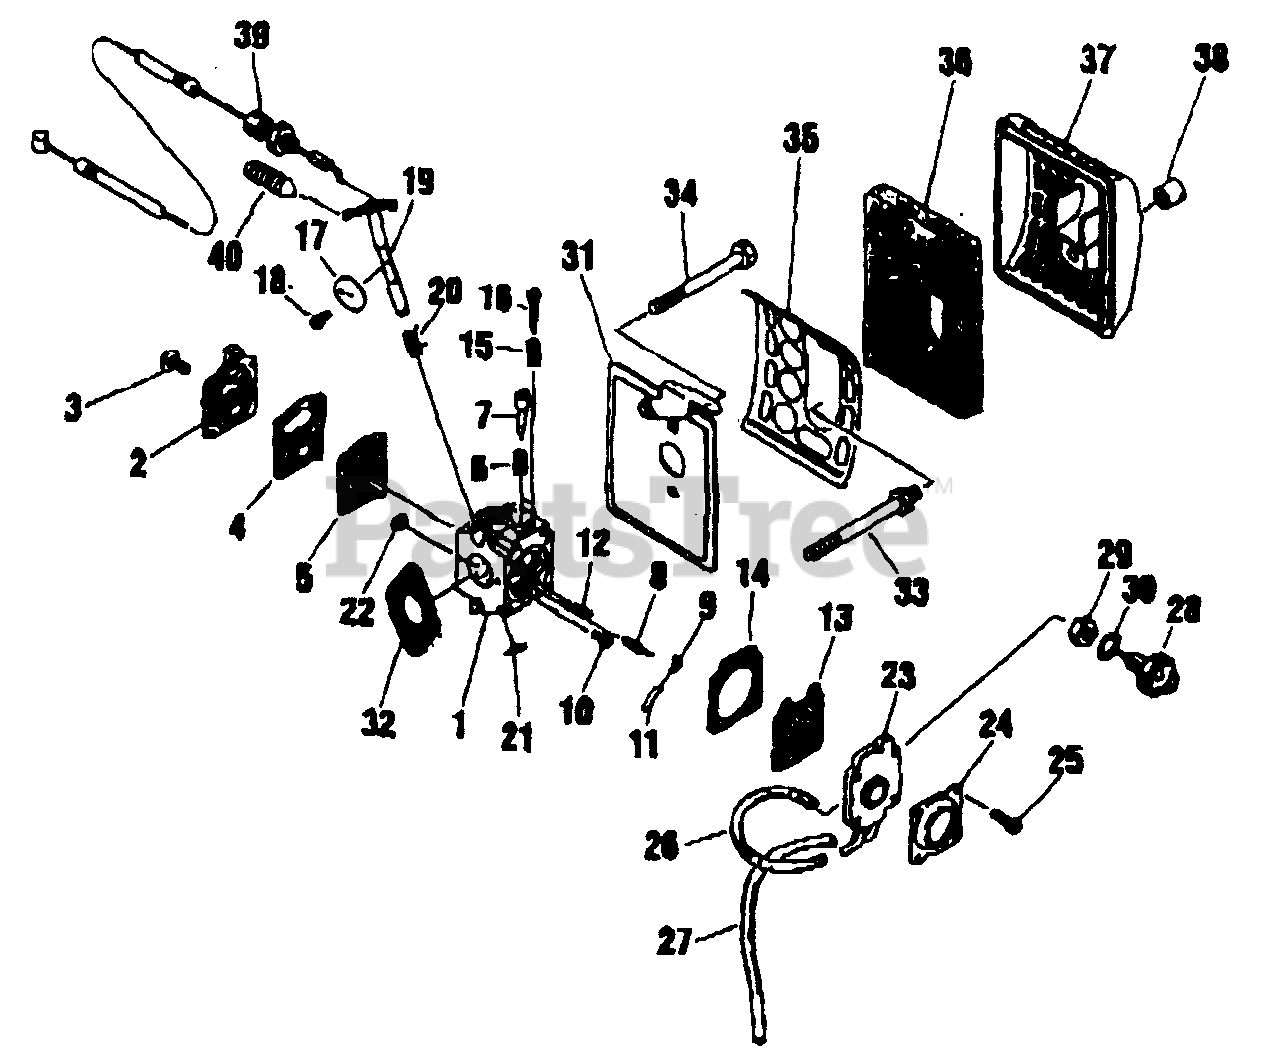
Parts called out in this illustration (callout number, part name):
1	BODY, CARBURETOR
2	COVER, PUMP
3	SCREW
4	GASKET, PUMP
5	DIAPHRAGM, PUMP
6	SPRING, NEEDLE
7	NEEDLE, LOW SPEED
8	VALVE, INLET NEEDLE
9	LEVER, METERING
10	SCREW, METERING LEVER PIN
10	SCREW
11	PIN, METERING LEVER
11	PIN
12	SPRING
13	DIAPHRAGM, METERING
14	GASKET, METERING
15	SPRING, NEEDLE
16	NEEDLE, HIGH SPEED
17	VALVE, THROTTLE
18	SCREW
19	SHAFT
20	SPRING
21	E-RING
22	SCREEN, FUEL INLET
23	STARTER BODY
24	RETAINER, PURGE BULB
26	PIPE, PURGE
27	HOSE, DRAIN
28	PRIMING PUMP
29	NUT
30	LOCKWASHER
31	CHOKE ASSY
32	GASKET, INTAKE
34	BOLT
35	PLATE, AIR FILTER
36	FILTER, AIR
37	COVER, AIR FILTER
38	NUT
39	CABLE, THROTTLE
40	SPRING, ADJUST
